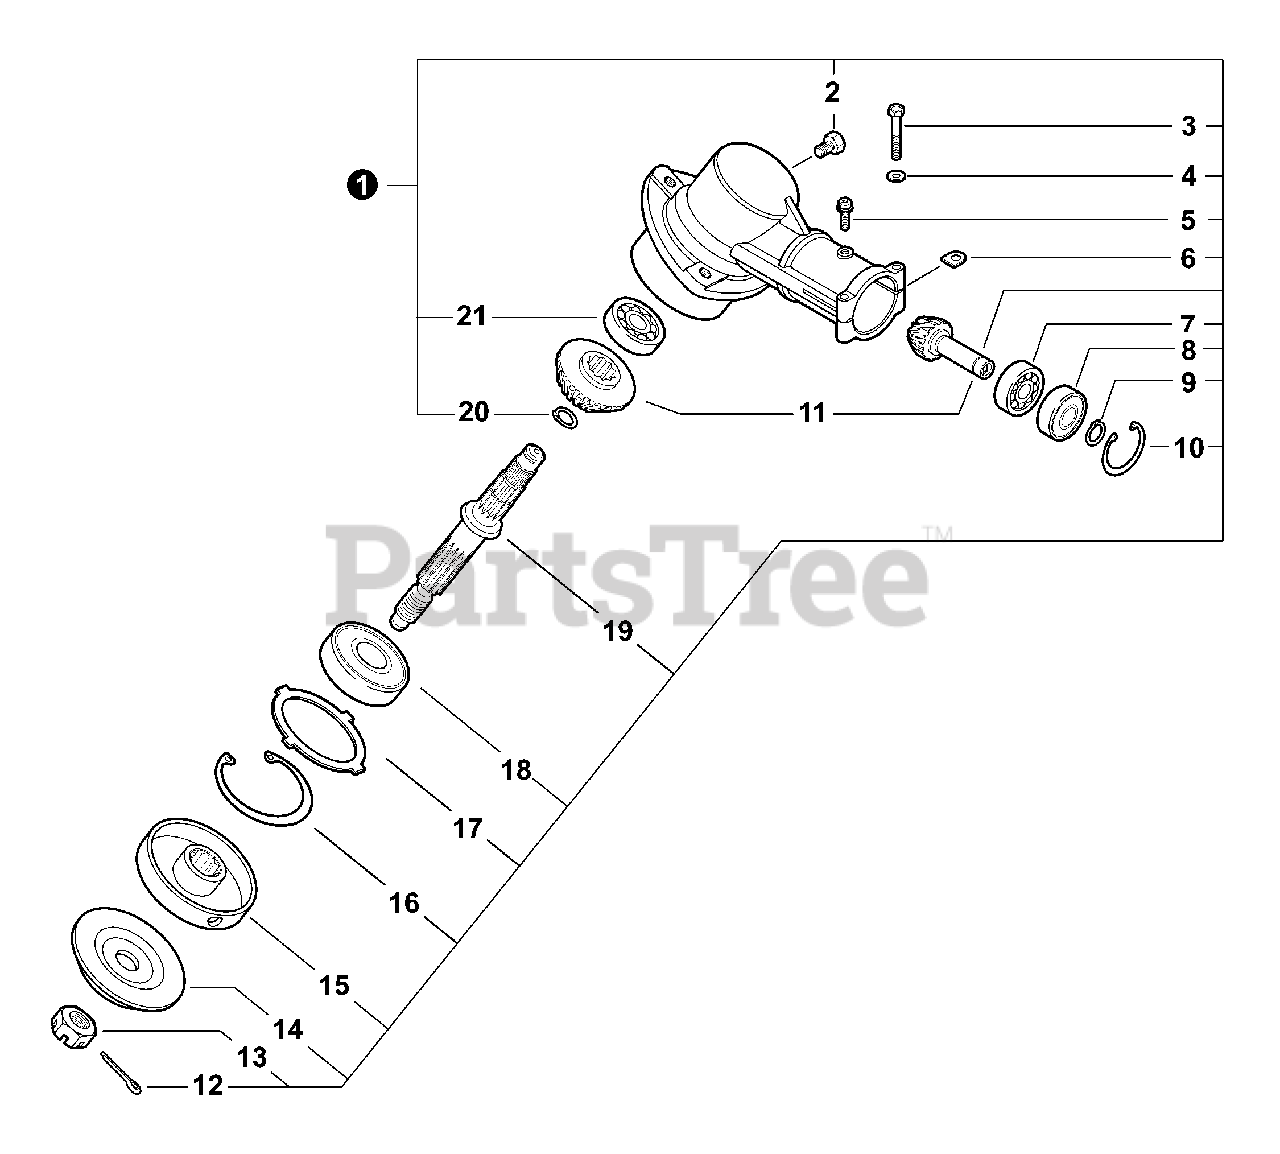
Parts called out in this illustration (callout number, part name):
1	GEAR CASE ASSY
2	SCREW 5×10
3	BOLT 5×35 SP
4	WASHER, FLAT 5.5×10×0.8
6	RING, SNAP Ø22
7	RING, SNAP Ø10
8	BEARING, BALL 6900Z
9	BEARING, BALL 6900
10	GEAR SET
11	BOLT M8×8
12	PIN, COTTER 2×22
14	PLATE, ADAPTOR - LOWER
15	PLATE, ADAPTOR - UPPER
17	RING, SNAP Ø32
18	BEARING, BALL 6201
19	SHAFT, GEAR
20	RING, SNAP Ø12
21	BEARING, BALL 609
